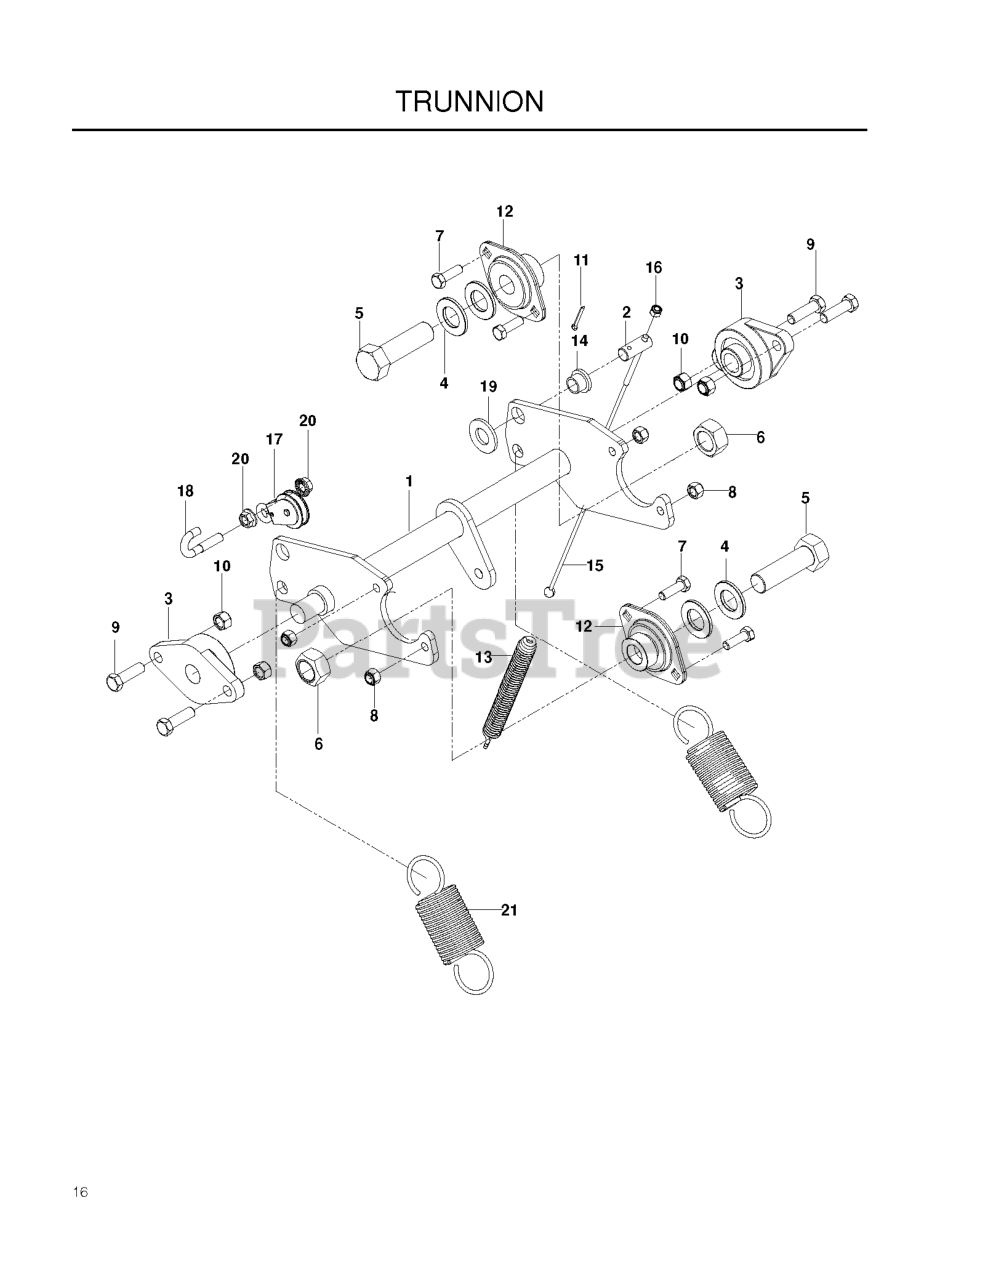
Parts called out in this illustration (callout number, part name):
1	TRUNNION SHAFT, BLACK
2	PIN - CABLE PIVOT
3	BEARING .75-2 BOLT
4	WASHER 3/4 FLAT SAE ZD
5	HCS 3/4-16 X 2-1/2 GR 5 ZD
6	NUT 3/4-16 HEX TOP LK ZD
7	HCS 5/16C X 1
8	NUT 5/16 NYLOC
9	HCS 3/8C X 1 1/4 GR5
10	NUT 3/8-16 NYLOC
11	PIN COTTER 1/8 X 1 ZD
12	FLANGE BEARING ZINC PLATED
13	SPRING - EXTENSION, CABLE
14	BUSHING, FLANGED NYLON
15	CABLE - PULL
16	NUT.1/4-20.HEX.NYLOC.ZD
17	BRACKET, PULLEY
19	WASHER 5/8 FLAT
20	NUT 5/16C WHIZ
21	SPRING - EXTENSION
